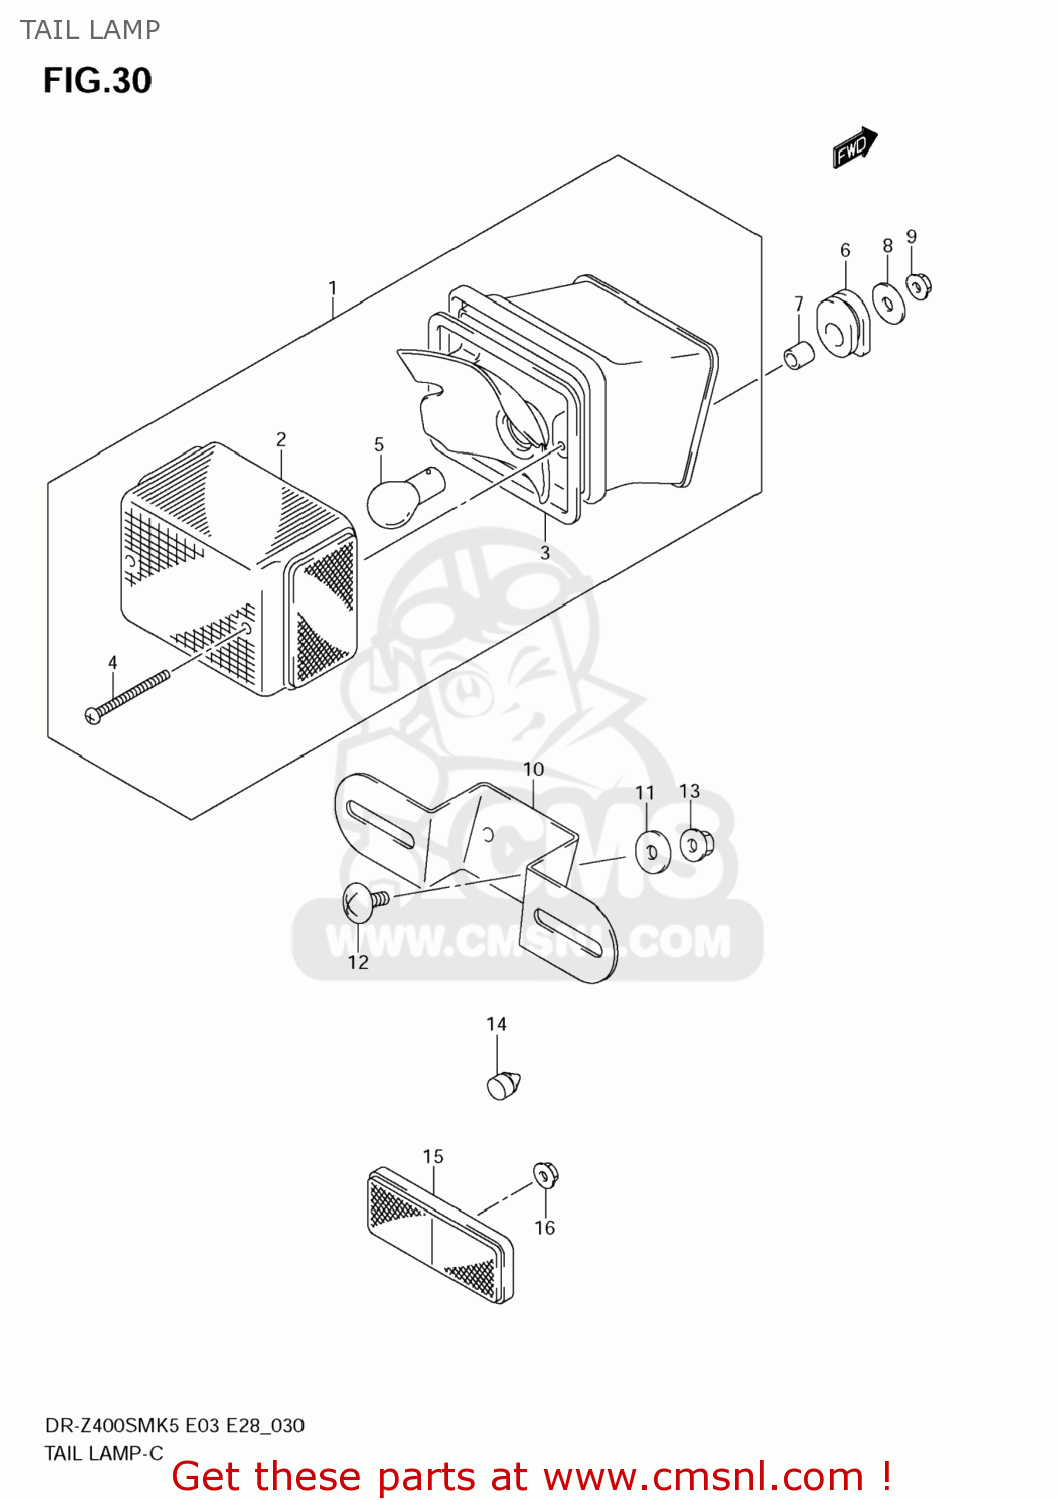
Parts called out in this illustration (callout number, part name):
1	LAMP ASSY,RR COMBINATION
2	LENS
3	GASKET,LENS (NAS)
4	SCREW(4X45)
5	BULB(12V21/5W)
6	CUSHION,RR COMBINATION
7	SPACER(6.5X10X10)
8	WASHER(6.5X20X1.6)
9	NUT
10	BRACKET,LICENSE PLATE
11	WASHER(6.5X20X1.6)
12	SCREW
13	NUT
14	CUSHION
15	REFLECTOR ASSY,RR
16	NUT
